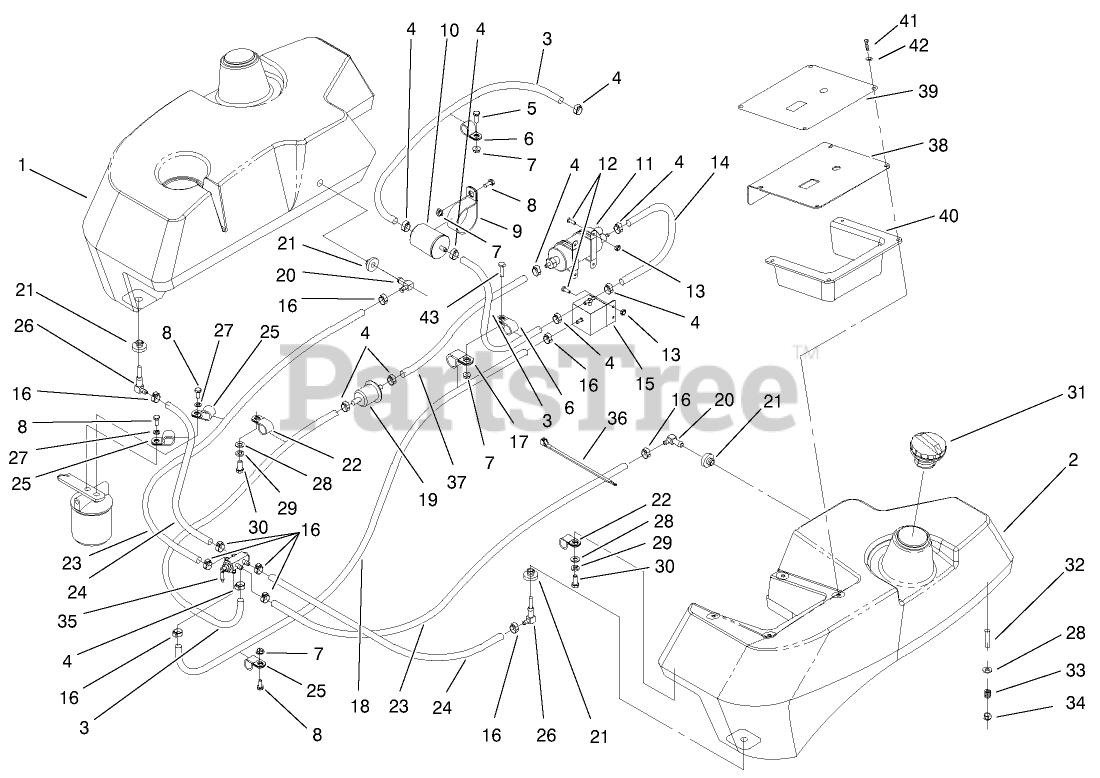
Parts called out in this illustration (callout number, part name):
1	TANK-FUEL, RH
2	TANK-FUEL, LH
3	Fuel Line
4	Clamp,Fuel Hose
5	SCREW-HH
6	Clip-Loom
7	NUT-HF
8	SCREW-HH
9	Clip-Loom
10	Kohler Fuel Filter
11	Kohler Fuel Pump
12	SCREW-HEAD, PAN
13	NUT-LOCK, NI
14	Fuel Line
15	Kohler Fuel Regulator
16	Clamp
17	Clip-Loom
18	Fuel Line
19	FILTER-FUEL
20	Elbow, 90
21	Bushing
22	Clip
23	Fuel Line
24	Fuel Line
25	Clip
26	Elbow
27	WASHER-LOCK
28	WASHER-PLAIN
29	WASHER-LOCK
30	SCREW-HH
31	CAP-FUEL
32	Stud
33	Spring-Fuel Tank
34	NUT-LOCK, NI
35	Valve-Fuel Line
36	Tie-Plastic
37	Fuel Line
38	PANEL-CONTROL
39	DECAL-PANEL, CONTROL
40	SHIELD-PANEL, CONTROL
41	Screw
42	Washer
43	SCREW-HH
